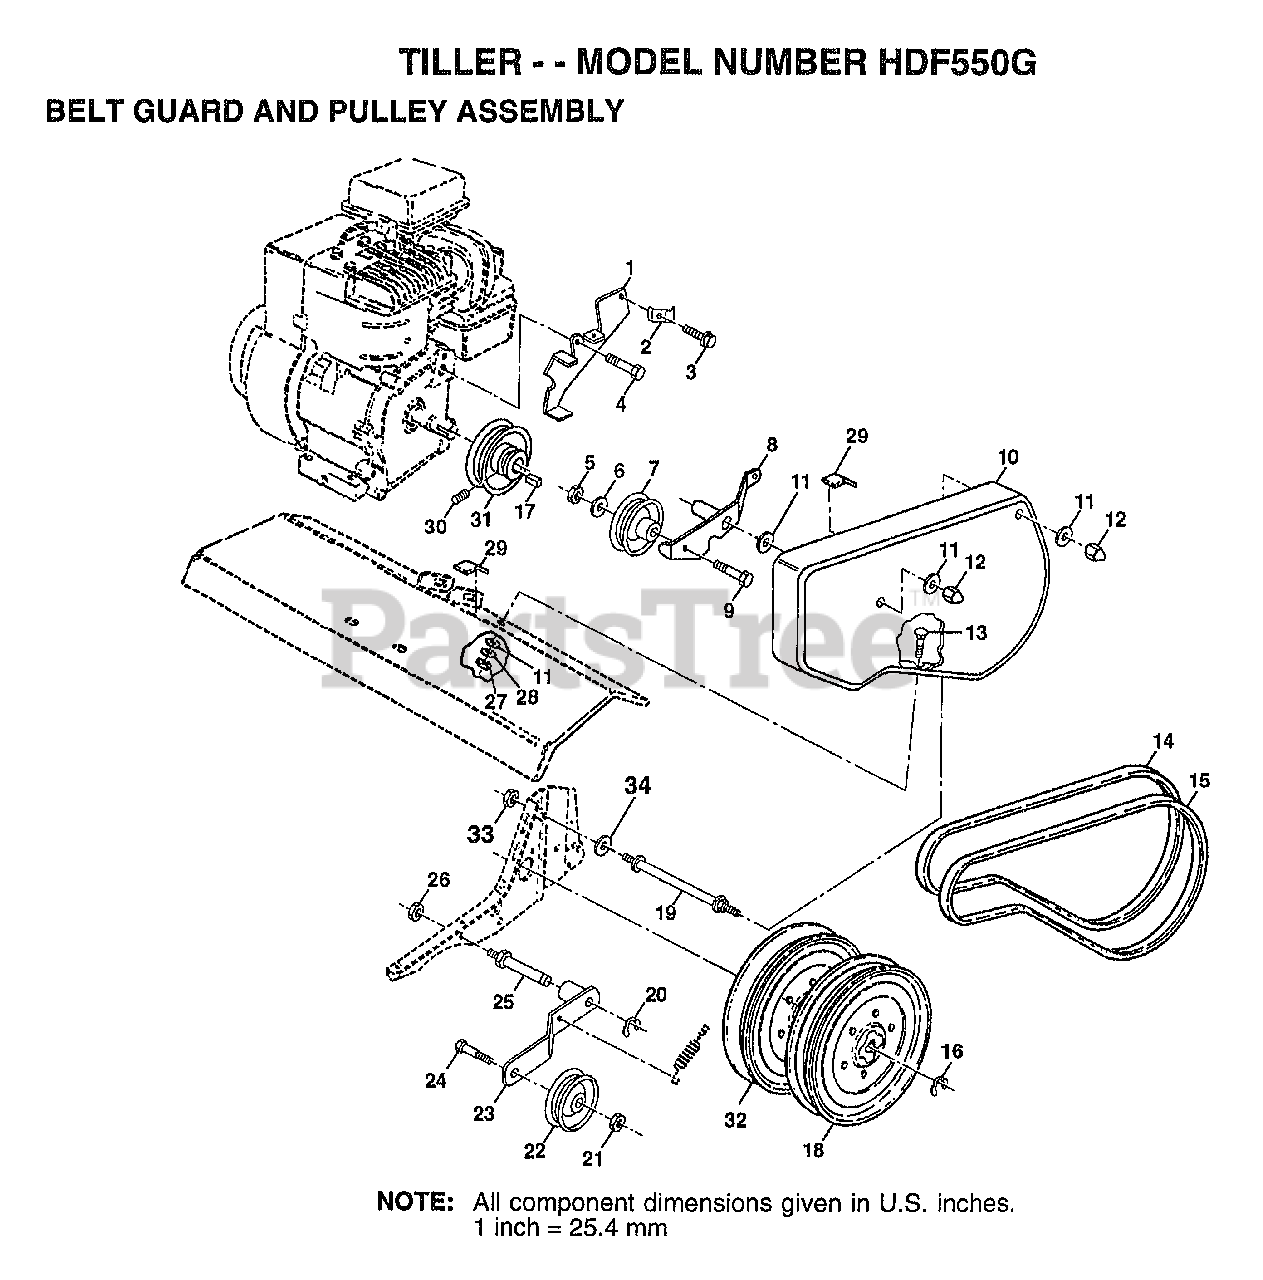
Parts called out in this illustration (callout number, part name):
1	ASM.BRKT.BELT.GRD
2	CONDIUT CLIP T
4	BOLT.HEX.HEAD
5	NUT.HEX.3/8-16UNC
6	WASHER
7	PULLEY W/SPACER
8	ARM.ASM.REV.IDLER
10	GUARD.PNT.BELT.MS-428
11	WASHER
12	NUT-CAP TI
13	BOLT T
14	BELT-V
17	KEY T
18	"SHEAVE,TRANS.""D"""
19	BOLT TI
20	KLIP RING TI
21	NUT
22	"PULLEY,IDLER"
23	"ARM, IDLER"
25	SHAFT IDLER TI
26	JAM NUT TI
28	LOCKWASHER
29	PAD IDLER TI
30	SET SCREW
31	ENGINE PULLEY TI
32	SHEAVE.TRANS
33	NUT
34	WASHER
